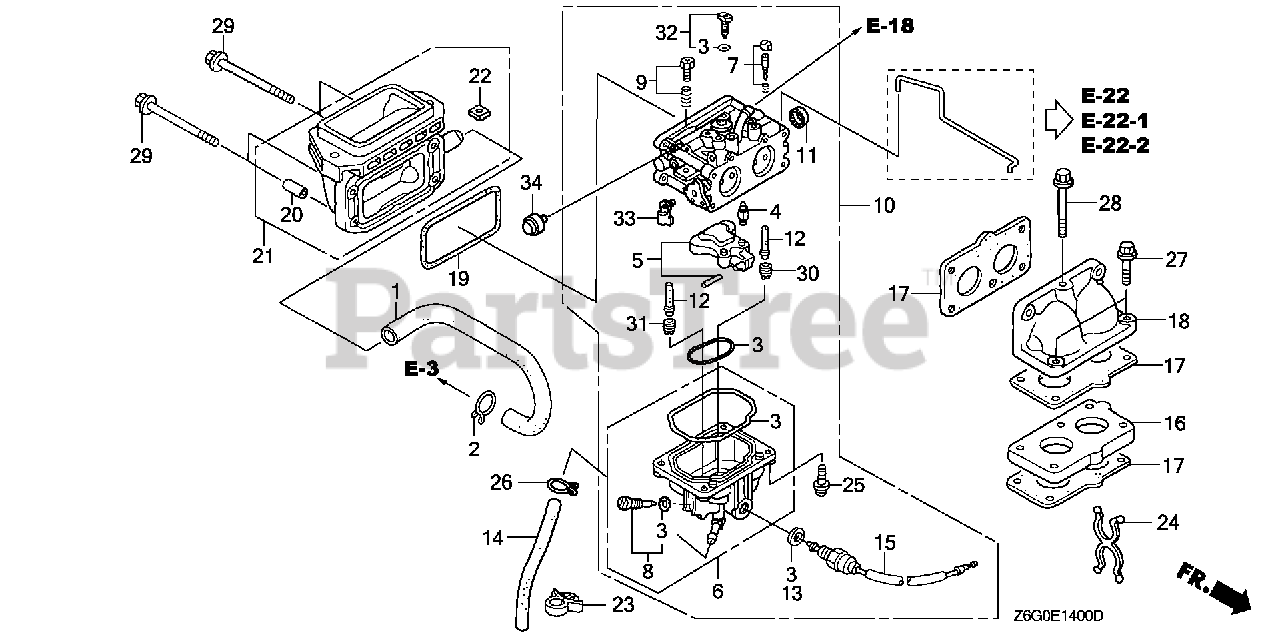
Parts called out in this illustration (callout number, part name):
1	TUBE, BREATHER
2	CLIP, BREATHER TUBE
3	GASKET SET (ADVENTURE GREEN) (CARBURETOR NO.)
4	VALVE SET, FLOAT (ADVENTURE GREEN) (CARBURETOR NO.)
5	FLOAT SET (ADVENTURE GREEN) (CARBURETOR NO.)
6	CHAMBER SET, FLOAT (ADVENTURE GREEN) (CARBURETOR NO.)
7	SCREW SET, PILOT (ADVENTURE GREEN) (CARBURETOR NO.)
8	SCREW SET, DRAIN (ADVENTURE GREEN) (CARBURETOR NO.)
9	SCREW SET, THROTTLE (ADVENTURE GREEN) (CARBURETOR NO.)
10	CARBURETOR ASSY. (BK01A B)
11	CAP, CHOKE LEVER DUST
12	NOZZLE, MAIN (CARBURETOR NO.)
13	WASHER, PLAIN (ADVENTURE GREEN) (CARBURETOR NO.)
14	TUBE, DRAIN
15	VALVE ASSY., SOLENOID (KEIHIN) (ADVENTURE GREEN) (CARBURETOR NO.)
16	INSULATOR, CARBURETOR
17	GASKET, CARBURETOR
18	ELBOW, MANIFOLD
19	GASKET, AIR CLEANER
20	COLLAR A, AIR CLEANER
21	ELBOW, AIR CLEANER
22	NUT, INSERT (6MM)
23	CLIP B, CABLE
24	CLIP, PURSE LOCK
25	SCREW, PAN (4X12)
26	CLIP, TUBE (B8)
27	BOLT, FLANGE (6X30)
28	BOLT, FLANGE (6X65)
29	BOLT, FLANGE (6X90)
30	JET, MAIN (#90) Use from Engine SN BE81B C.
30	JET, MAIN (#95)
30	JET, MAIN (#100) Use from Engine SN BE87A A to BE87A A.
31	JET, MAIN (#90) Use from Engine SN BE81B C.
31	JET, MAIN (#95)
31	JET, MAIN (#100) Use from Engine SN BE87A A to BE87A A.
32	JET SET, PILOT (#40) (ADVENTURE GREEN) (CARBURETOR NO.)
33	ARM, THROTTLE LINKAGE (CARBURETOR NO.)
34	FILTER ASSY., AIR VENT
